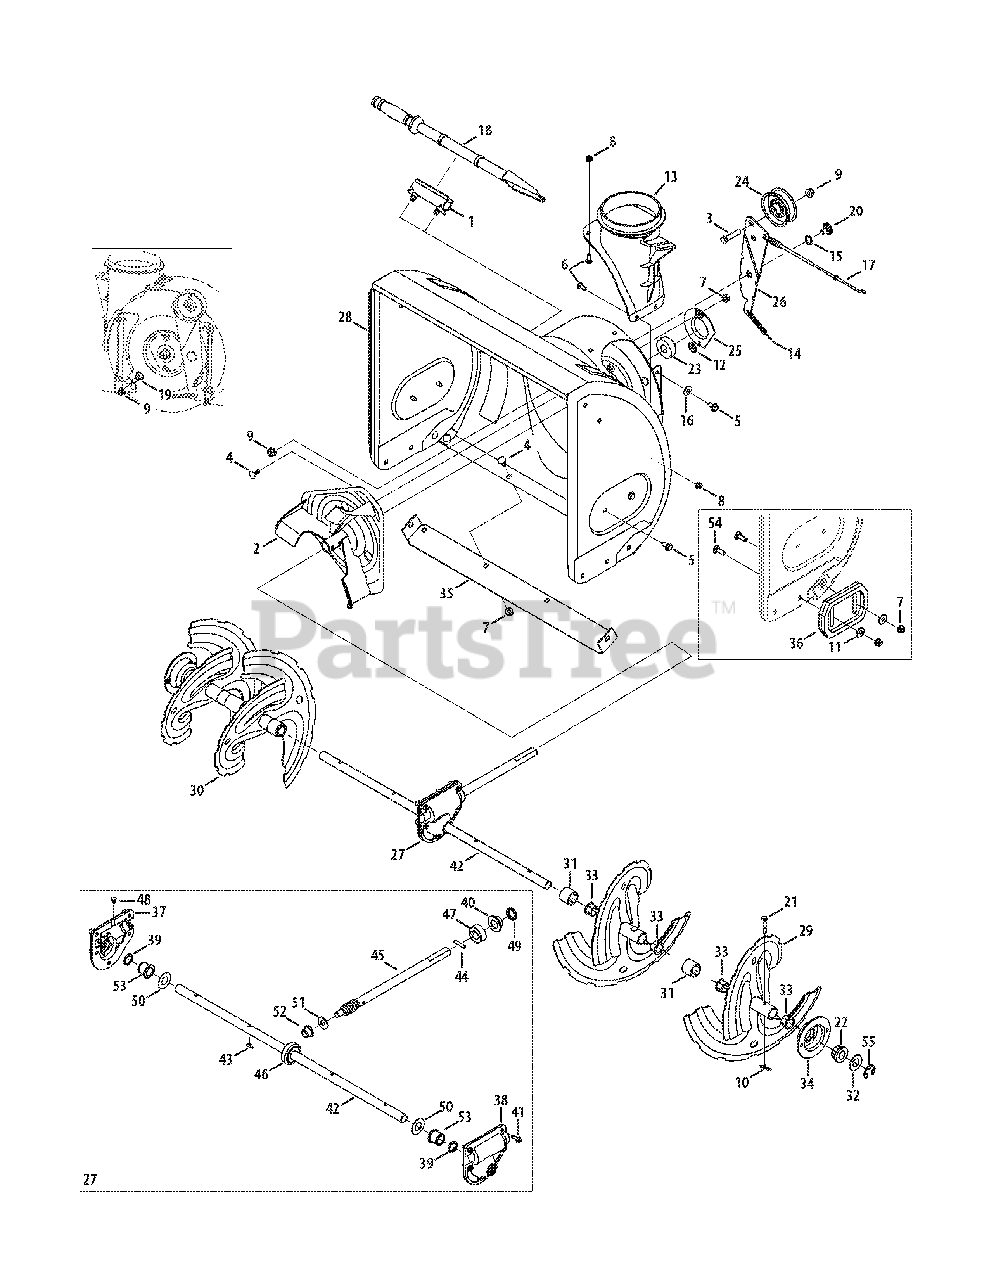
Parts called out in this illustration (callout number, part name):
1	Snow Removal Tool Mount
2	Impeller Assembly, 12" Dia.
3	Hex Screw, 3/8-16, 1.75, Gr5
4	Bolt, Carriage, 5/16-18, .750 Gr1
5	Screw, 5/16-18, 0.750
6	Screw, Carriage, 1/4-20, .750, Gr5
7	Nut, Flange Lock, 5/16-18, Nylon
8	Nut, Flange Lock, 1/4-20, Nylon
9	Nut, Flange Lock, 3/8-16, Nylon
10	Cotter Pin, Bow-tie
11	Washer, Flat, .349 x .879 x .063
12	Nut, Push-on, .25 Dia
13	Chute, Adapter 5" Dia
14	Spring, Extension, .38 OD x 4.59
15	Washer, Wave, .625 x .885 x .015
16	Washer, Bell, .340 x .872 x .060
17	Clutch Cable, Auger, 47.23"
18	Snow Removal Tool
19	Screw, Shoulder, .498 x .34, 3/8-16
20	Screw, Shoulder, .625 x .17, 3/8-16
21	Shear Pin, .25 x 1.50
22	Bearing, Hex Flange x .75 ID
23	Bearing, Ball, .75 ID x 1.85 OD
24	Flat Pulley, Idler, 2.75 OD
25	Housing, Bearing, 1.85 ID
26	Bracket, Auger Idler w/ Brake
27	Gearbox Assembly, Auger, 24"
28	Housing Assembly, Auger 24"
29	Spiral Assembly, LH
30	Spiral Assembly, RH
31	Spacer, 1.25 OD x .75 ID x 1.00
32	Washer, Flat, .76 x 1.49 x .06
33	Bushing, Flange, .80 ID x .91 OD
34	Housing, 1" Hex Bearing
35	Shave Plate, 2.25 x 23.66
36	Slide Shoe Standard Polymer
36	Skid Shoe Kit, Standard Polymer Reversible
37	Housing, Auger, RH Reduced
38	Housing, Auger, LH Reduced
39	Seal, Oil, .750 x 1.00 x .125
40	Bearing, Flange, .75 x 1.0 x .59
41	Screw, Self-tapping, 1/4-20, 0.750
42	Axle, Auger, 24"
43	Key, Hi-pro 3/16 x 5/8
44	Pin, Dowel, .25 OD x 1.2
45	Shaft, Worm .75 OD
46	Gear, Worm 20T
47	Collar, Thrust
48	Plug, 1/4 x .437
49	Seal, Oil, .75 x 1 x .131
50	Washer, Flat, .760 ID x 1.5 OD
51	Washer, Flat, .51 x 1.12
52	Bearing, Flange, .75 x 1.0 x .925
53	Bearing, Flange, .75 x 1.00 x .975
54	Screw, Carriage, 5/16-18 x 1.00
55	E-Ring
